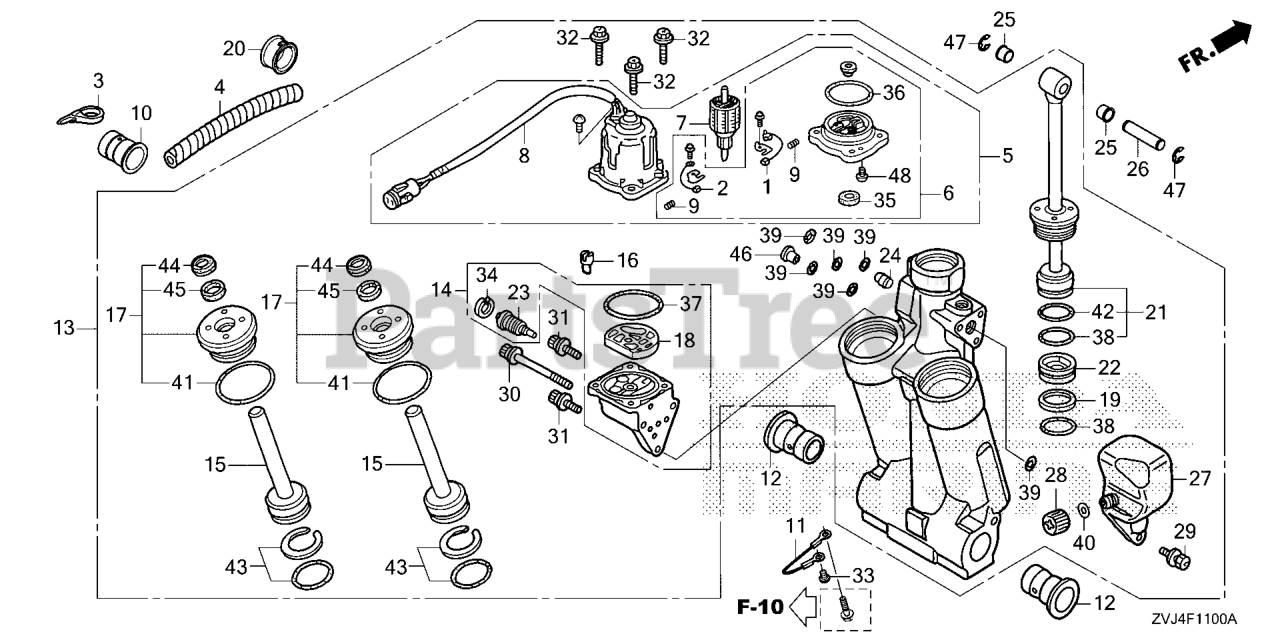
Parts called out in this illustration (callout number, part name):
1	BREAKER ASSY.
2	BRUSH ASSY.
3	BAND (BLACK 3.5X140)
4	TUBE, SPIRAL (12X14.6)
5	MOTOR ASSY., POWER TILT
5	MOTOR, POWER TILT
6	BRACKET ASSY.
8	YOKE ASSY.
9	SPRING, MOTOR
10	GROMMET, CASE (LOWER) (C)
11	WIRE, LEAD (1.5X116MM)
12	BUSH, SWIVEL CASE
13	TRIM-TILT ASSY., POWER
13	TRIM/TILT, POWER
14	PUMP ASSY.
15	ROD, PISTON (B)
16	JOINT, DRIVE
17	GUIDE, ROD
18	FILTER (B)
19	RING, BACK-UP
20	BUSH, MOTOR CODE
21	ROD, PISTON
22	PISTON, FREE
23	VALVE, MANUAL
24	VALVE, RESERVOIR
25	BUSH, CYLINDER (LOWER)
26	PIN, CYLINDER (UPPER)
27	TANK, OIL
28	CAP, OIL TANK
29	BOLT, RECESSED
30	BOLT A, SOCKET
31	BOLT B, SOCKET
32	BOLT, HEX.
33	SCREW, PAN (6X8)
34	CIRCLIP (INNER)
36	O-RING (2.0X70.5)
37	O-RING (1.8X69.6)
38	O-RING (3.5X38.7)
39	O-RING (1.68X7.25)
40	O-RING (1.9X11)
41	O-RING (3.5X35.7)
42	O-RING (3.5X41.7)
43	O-RING SET (3.5X31.7)
44	SEAL, WATER
46	COLLAR, ORIFICE
47	E-RING (15MM)
48	SCREW (4X16)
